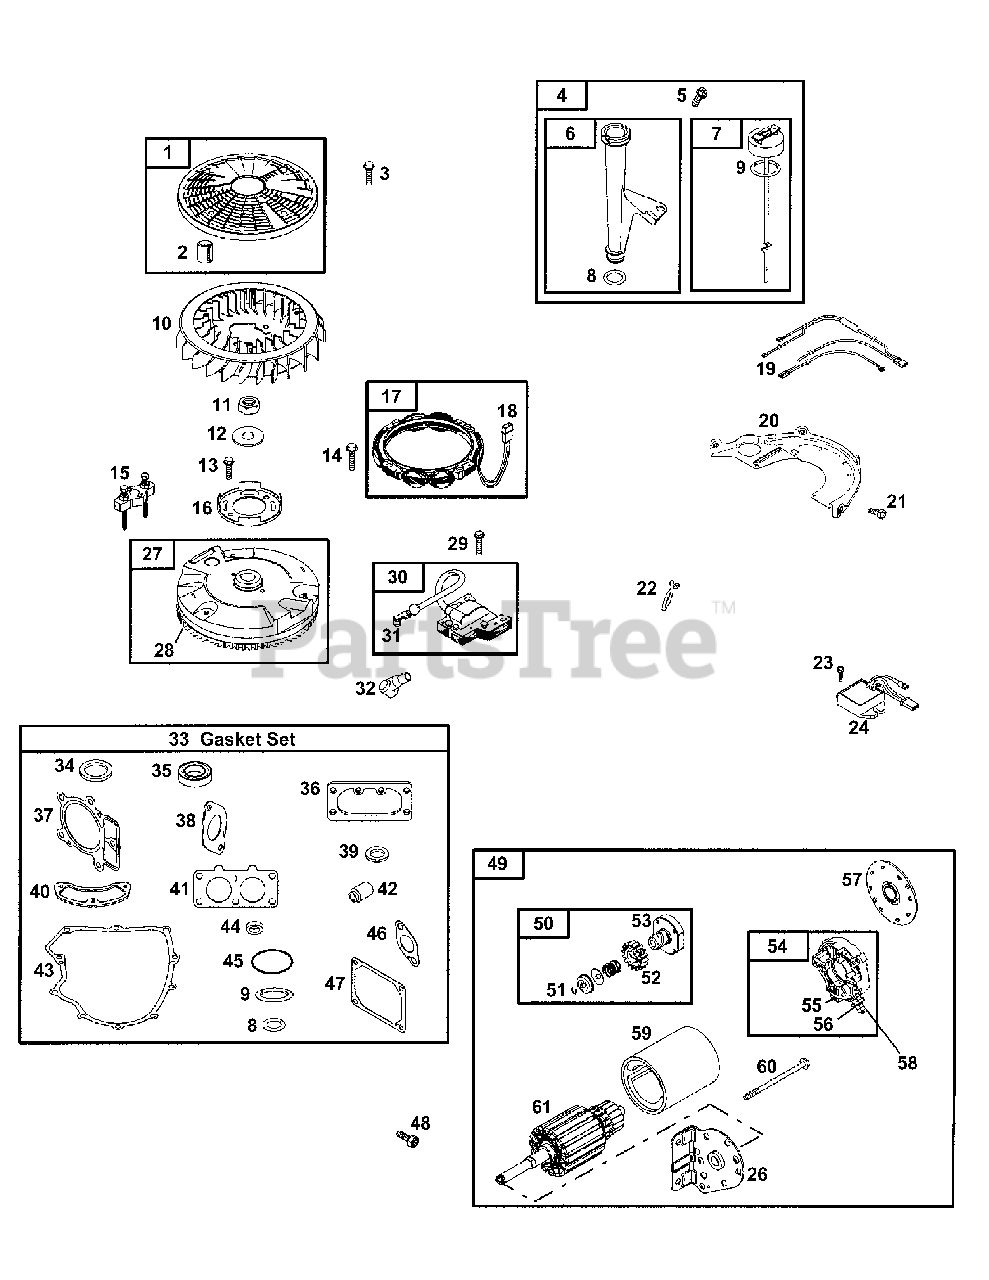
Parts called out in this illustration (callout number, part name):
1	Rotating Screen
3	Screw (Rotating Screen)
4	Dipstick/Tube Assembly
5	Screw (Dipstick Tube)
6	Dipstick Tube
7	Dipstick
8	Dipstick Tube Seal
9	Dipstick/Tube Seal
10	Flywheel Fan
11	Nut (Flywheel)
12	Washer (Flywheel)
13	Screw (Fan-Retainer)
14	Screw (Alternator)
15	Flywheel Puller
16	Fan Retainer
17	Alternator (Dual Circuit)
18	Alternator Connector/Wire
19	Wiring Harness
20	Back Plate
21	Screw (Back Plate)
23	Screw (Regulator)
24	Regulator (Regulated-16 Amp)
27	Flywheel
29	Screw (Magneto Armature)
30	Magneto Armature
31	Sparkplug Terminal
32	Sparkplug Boot
33	Engine Gasket Set
34	Oil Seal (Magneto Side)
35	Oil Seal (PTO Side)
36	Air Cleaner Gasket
37	Cylinder Head Gasket
38	Intake Gasket
39	Sealing Washer
40	Breather Gasket
41	Intake Gasket
42	Valve Seal
43	Crankcase Gasket
44	Governor Shaft Seal
45	O-Ring Seal (Oil Pump Cover)
46	Exhaust Gasket
47	Rocker Cover Gasket
48	Screw (Drive Cap)
49	Starter Motor
50	Starter Drive
51	Retaining Ring
52	Pinion Gear
53	Drive Clutch
54	Brush Retainer
56	Nut (Brush Retainer)
58	Nut (Brush Retainer)
59	Housing-Starter
60	Bolt (Starter Motor)
61	Armature (Serviced By Starter Only)
